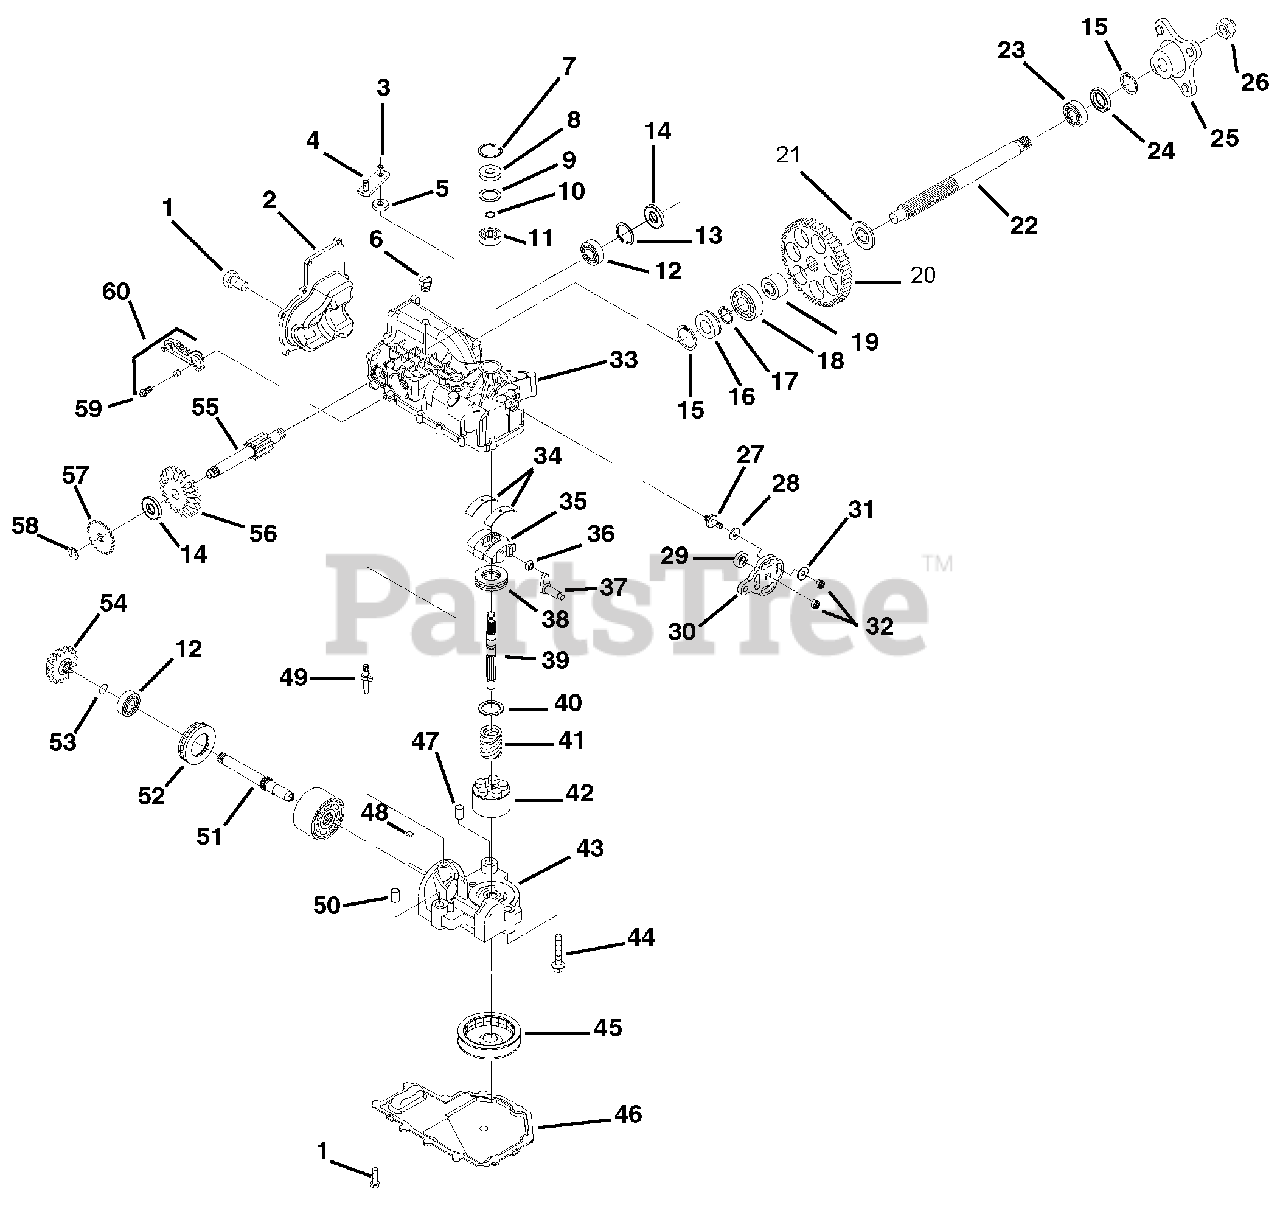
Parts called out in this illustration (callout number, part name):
1	Screw .25-20 x .75
2	Cover-Back
3	Ring-Retaining
4	Arm-Bypass
5	Seal-Lip
6	Plug-Plastic
7	Ring-Retaining
8	Seal-Lip
9	Spacer
10	Ring-Wire Retaining
11	Bearing-Ball
12	Bearing-Ball
13	Ring-Retaining
14	Seal-Brake Shaft
15	Ring-Retaining - Axle
16	Seal-Plug - Side
17	Ring-Retaining - Axle
18	Bearing-Ball 20 x 47 x 14
19	Bushing-Axle
20	Gear-Spur 53T
21	Bushing-Axle
22	Shaft-Axle
23	Bearing-Ball 25 x 47 x 12
24	Seal
25	Assembly-Hub
26	Nut-Hex 3/4-16
27	Stud-Short 5/16-24
28	Friction Puck
29	Seal, Lip
30	Arm-Control
31	Washer
32	Nut
33	Assembly-Upper Housing
34	Bearing-Cradle
35	Variable Swashplate
36	Slot Guide
37	Arm-Trunnion
38	Bearing-Thrust 30 x 52 x 13
39	Shaft-Input
40	Washer-Block Thrust
41	Spring-Block
42	Assembly-Cylinder Block 10cc
43	Assembly-Center Section
44	Screw
45	Filter
46	Housing-Lower
47	Pin-Alignment
48	Bypass Plate
49	Bypass Actuator
50	Assembly-Cylinder Block 21cc
51	Shaft-Motor
52	Bearing-Thrust 42 x 68 x 16
53	Ring-Wire Retaining
54	Gear-Bevel 14T
55	Kit, Brake Shaft
56	Gear-Bevel 19T
57	Brake Disc
58	Ring-Retaining
59	Screw-He-Washer-Head .25-20 x .875
60	Assembly-Left Hand Brake Arm
